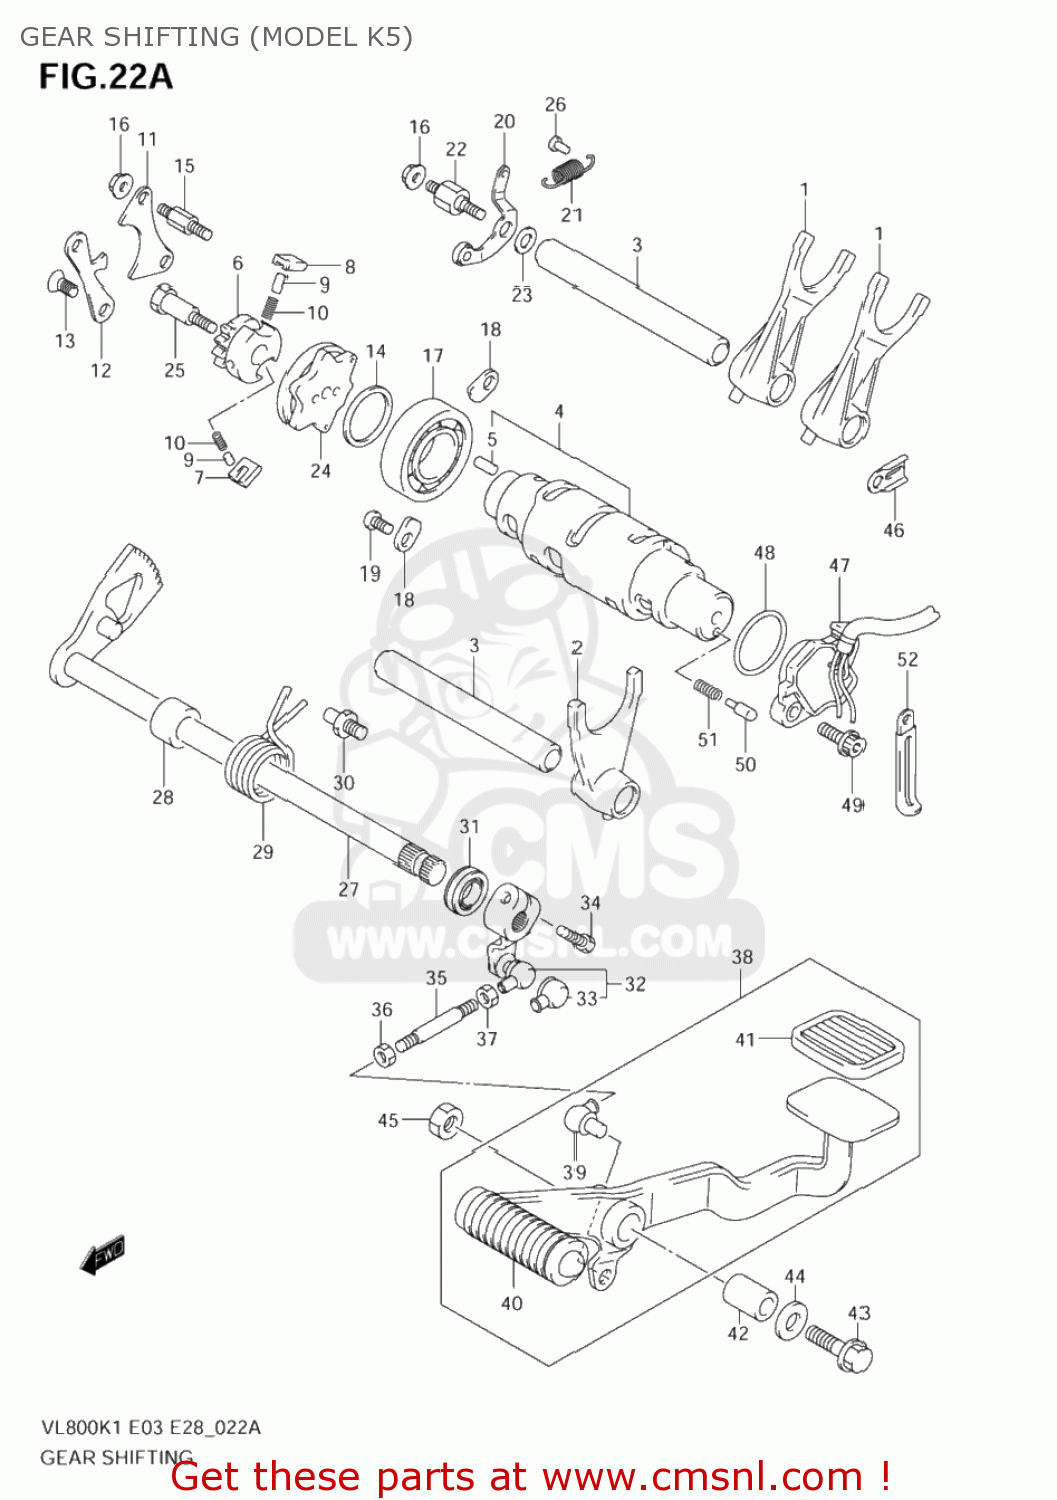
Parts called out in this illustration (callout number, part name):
1	FORK,GEAR SHIFT NO.1
2	FORK,GEAR SHIFT NO.2
3	SHAFT,GEAR SHIFT FORK(L:115)
4	CAM,GEAR SHIFT
5	PIN
6	GEAR,GEAR SHIFT CAM DRIVEN
7	PAWL,GEAR SHIFT NO.1
8	PAWL,GEAR SHIFT NO.2
9	PIN(5X8)
10	SPRING
11	LIFTER,GEAR SHIFT POLE
12	GUIDE,GEAR SHIFT CAM
13	SCREW(6X12)
14	WASHER(25X32X3)
15	BOSS,SHIFT POLE LIFTER
16	NUT
17	BEARING(25X47X8)
18	RETAINER
19	SCREW(6X12)
20	STOPPER,GEAR SHIFT CAM
21	SPRING
22	SUPPORT,CAM STOPPER ARM
23	WASHER
24	PLATE,GEAR SHIFT CAM
25	PIN,SHIFT CAM DRIVEN GEAR
26	RIVET
27	SHAFT,GEAR SHIFT
28	SPACER(12X20X15.3)
29	SPRING
30	STOPPER,GEAR SHIFT ARM
31	OIL SEAL
32	ARM,GEAR SHIFT LINK
33	COVER,DUST
34	BOLT
35	ROD,GEAR SHIFT LINK
36	NUT
37	NUT
38	LEVER ASSY,GEAR SHIFT
39	COVER,DUST
40	RUBBER
41	RUBBER,BRAKE PEDAL
42	SPSCER,GEAR SHIFT LEVER
43	BOLT(10X40)
44	WASHER (10.5X24X2.3)
45	NUT
46	CLAMP,GENERATOR LEAD WIRE
47	BASE ASSY,GEAR
48	O RING(D:2.4,ID:25.7)
49	BOLT
50	PIN(5X15.5)
51	SPRING
52	CLAMP(L:45)
